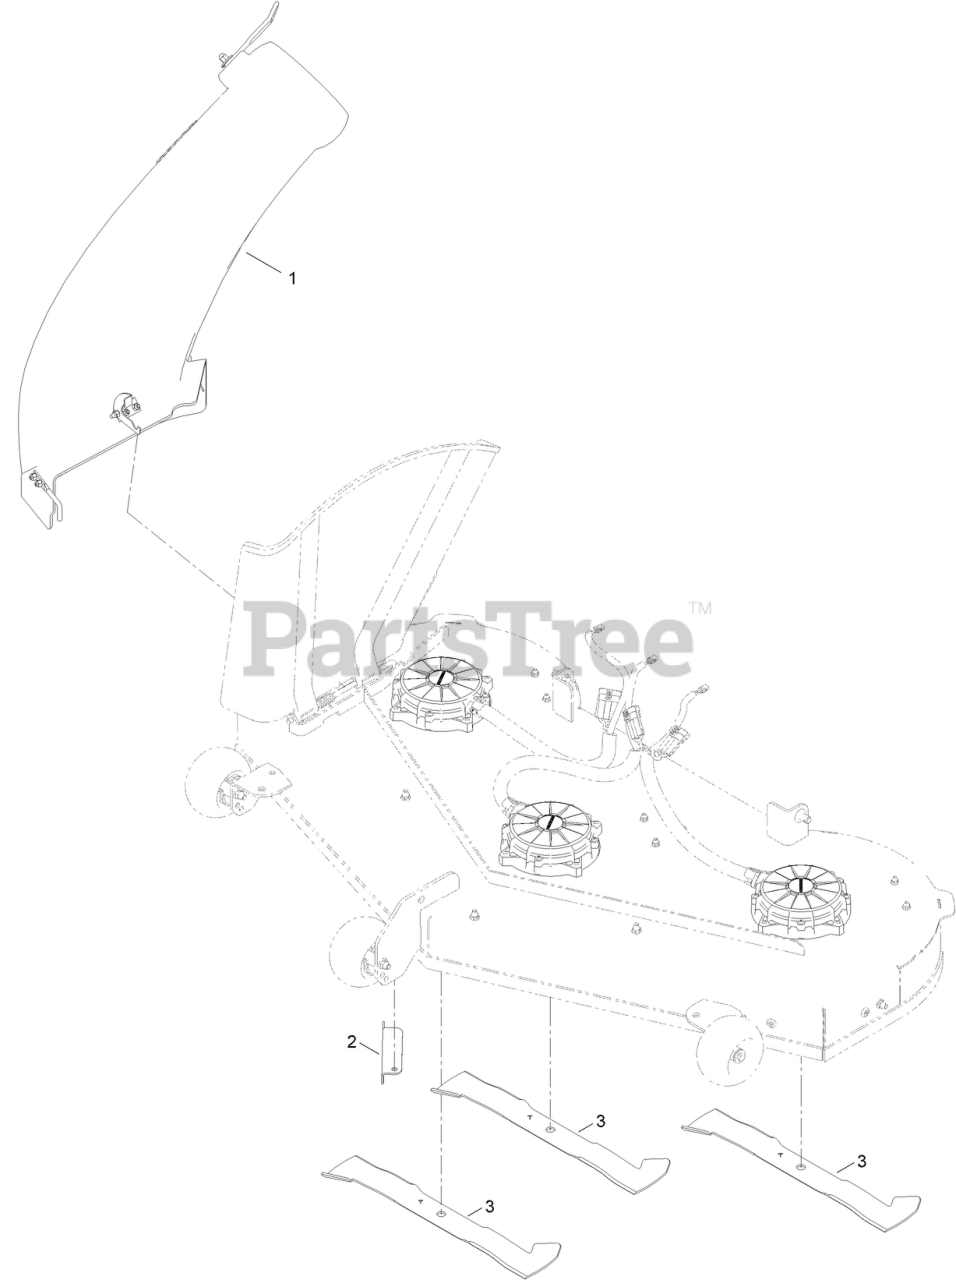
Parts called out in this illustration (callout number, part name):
1	50/54 BOOT ASSEMBLY
2	BAFFLE-CUTOFF
3	BLADE-18.75 IN, BAGGING
